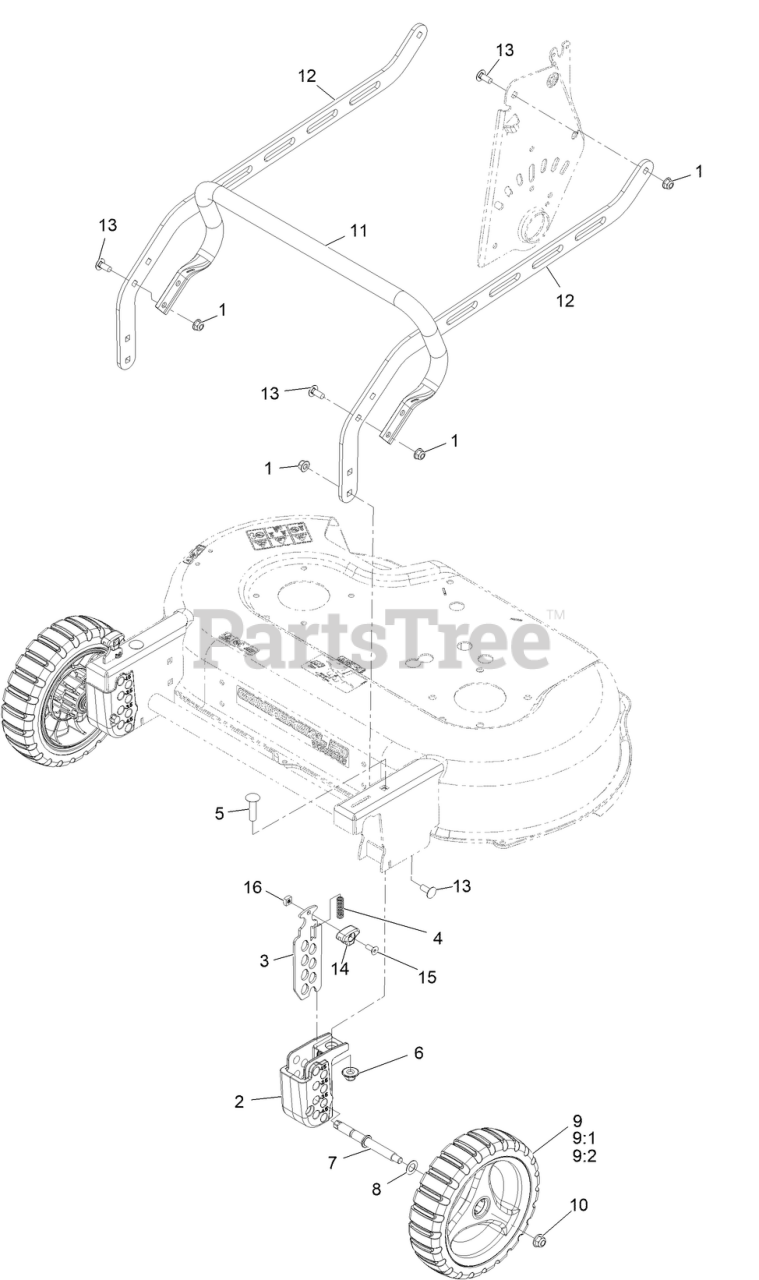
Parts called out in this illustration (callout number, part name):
1	NUT-HF, NI
2	BLOCK-FRONT QUADRANT
3	PLATE-ADJUSTER
4	SPRING-COMPRESSION
5	SCREW-CARR
6	Nut-Nyloc 3/8-16 Flg
7	AXLE-WHEEL
8	WASHER-PLAIN
9	WHEEL ASM, 9" W/BEARINGS
9:1	WHEEL ASM, 9
9:2	BEARING-BALL
10	NUT-HF, NI
11	GUARD-ECV30 FRONT MOTOR
13	SCREW-CARR
14	GRIP-HOC HANDLE
15	SCREW-HSFH
16	Square Nut 1/4-20,ATV CB
